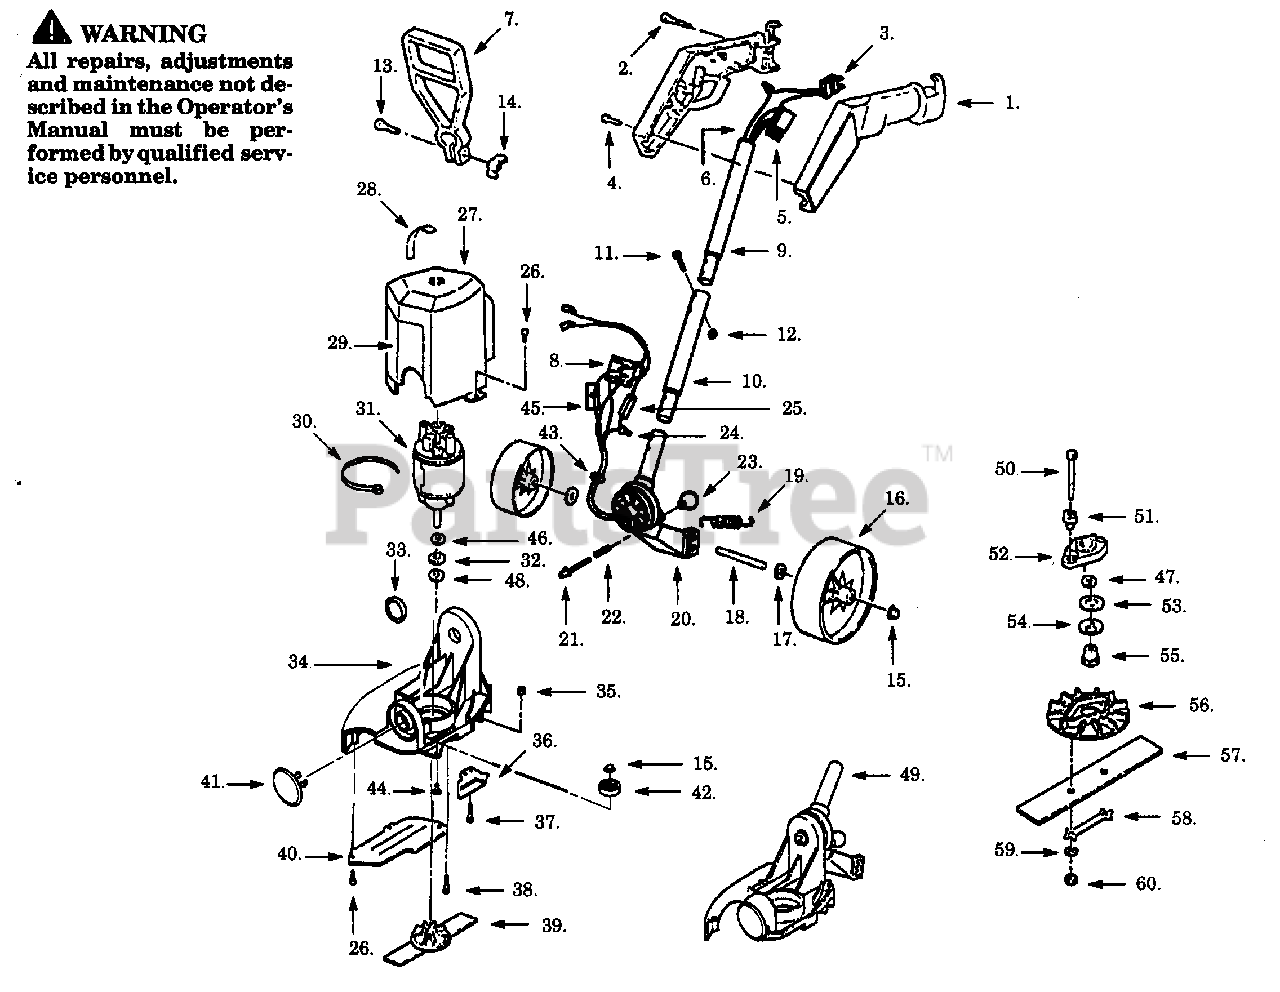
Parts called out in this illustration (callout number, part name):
1	Handle Set
3	Power Plug
6	Harness Ass'y.
7	Assist Handle
8	Bridge Ass'y.
9	Upper Tube
10	Lower Tube
12	Locknut
14	Wing Nut
15	Push Nut
16	Rear Wheel
18	Rear Axle
20	Rear Swivel
21	Swivel Lock Shaft
22	Swivel Lock Spring
24	Terminal Cap
25	Resister
27	Motor Cover
28	Rear Adjust Label (Not a serviceable part)
29	Motor Cover Label
30	Tie Wrap
31	Motor Ass'y.
33	Retaining Ring
34	Deck Frame
36	Blade Guide
39	Blade Ass'y.
40	Side Guard Plate
46	Retaining Ring
49	Edger Frame Ass'y.
51	Insulating Sleeve
52	Clutch Plate
54	Spring Washer
55	Clutch Sleeve
58	Lock Strap
59	Lockwasher
